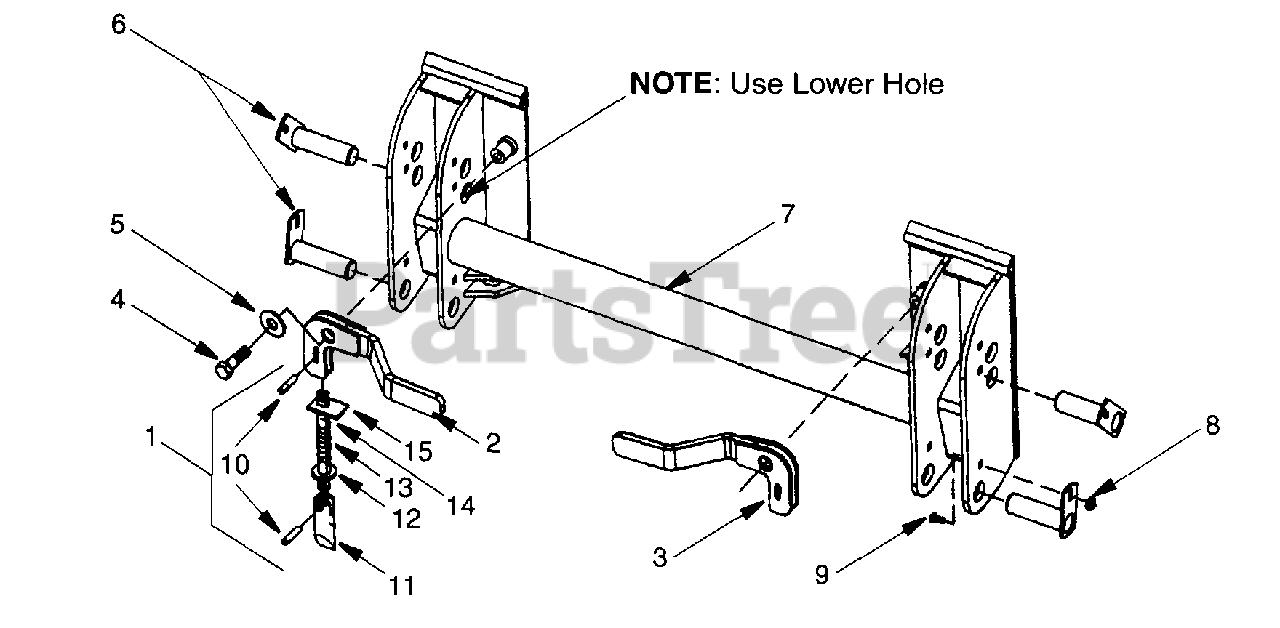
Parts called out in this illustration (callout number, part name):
1	Handle Repair Kit
2	Left Handle
3	Right Handle
4	Hex Cap Screw, GR5 1/2 x 1
5	Washer, 1/2
6	Pin Weldment
7	Attachment Coupler
8	Flange Lock Nut, 3/8
9	Carriage Bolt, 3/8 x 1
10	Drive-Lok Pin
11	Pin
12	Washer
13	Compression Spring
14	Link
15	Washer
